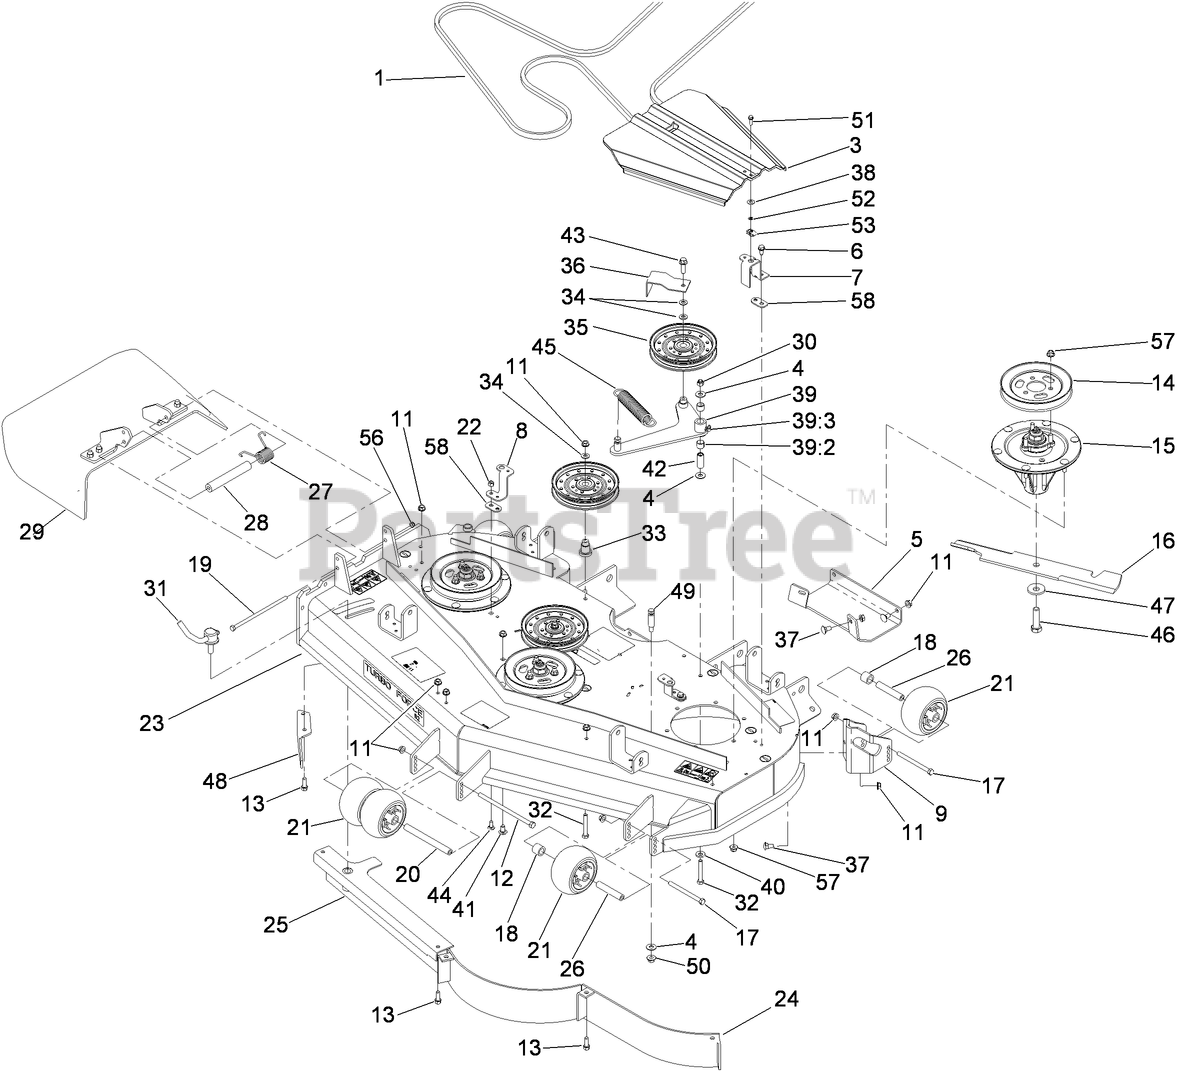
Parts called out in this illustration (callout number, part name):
1	BELT-V
3	COVER-BELT
4	WASHER-FLAT
5	Plate-Skid
6	SCREW-HWHTF
7	BRACKET-COVER
8	BRACKET-COVER, TALL
9	MOUNT-WHEEL, LH
11	NUT-HHF, WHIZ
12	SCREW-HH
13	SCREW-HWH
14	PULLEY-B SECTION
15	SPINDLE ASM
16	BLADE-18IN, HI FLOW
17	SCREW-HH
18	TUBE-SPACER
19	SCREW-HH
20	SPACER-WHEEL
21	ROLLER-SCALP, ANTI
22	NUT-LOCK, NI
23	DECK DECAL ASM
26	TUBE-SPANNER
27	SPRING-TORSION
28	SPACER
29	RUBBER DEFLECTOR ASM
30	NUT-LOCK, NI
31	LEVER ASM
32	SCREW-HH
33	MOUNT-PULLEY
34	WASHER-FLAT
35	Idler-Flat
36	GUIDE-BELT
37	SCREW-CARR
38	WASHER-THRUST
39	DECK IDLER ARM ASM
39:2	SLEEVE-BEARING
39:3	FITTING-GREASE, 90 DEG
40	WASHER-BELLEVILLE
41	SCREW-CARR
42	BUSHING
43	SCREW-HHF
44	SCREW-CARR
45	SPRING-EXTENSION
46	SCREW-BLADE
47	Washer-Blade Bolt, Heavy
48	BAFFLE-DISCHARGE
49	PIN-THREADED, SPRING ANCHOR
50	NUT-HF
51	SCREW-HWH
52	NUT-RETAINER
56	NUT-LOCK, NI
57	NUT-HF, NI
58	SPACER-BELT COVER
